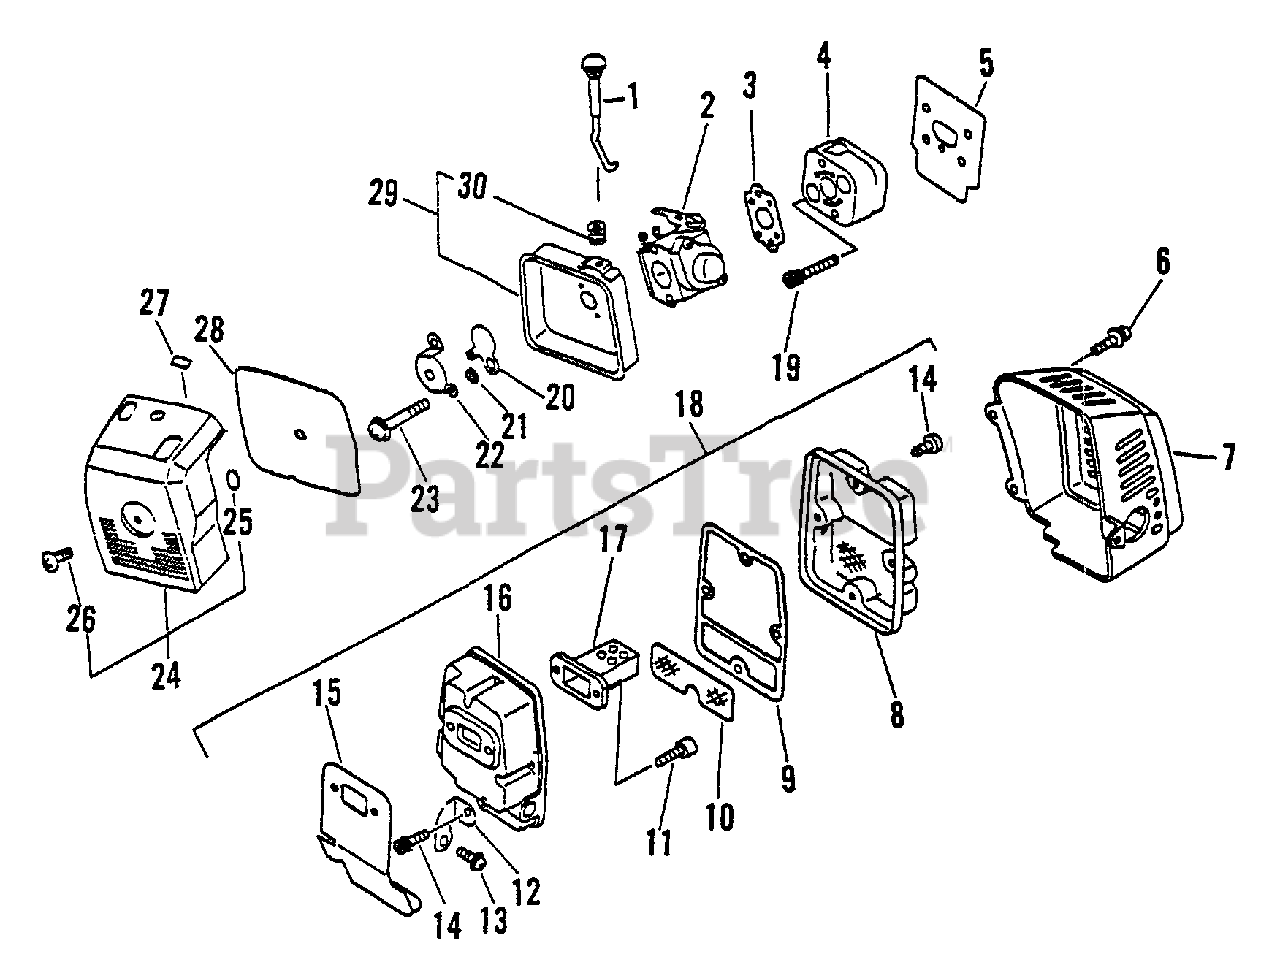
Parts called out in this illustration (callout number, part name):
1	ROD, CHOKE
2	CARBURETOR C1U-K21
3	GASKET, INTAKE
4	INSULATOR
5	GASKET, INTAKE
6	SCREW - 4X8
7	COVER, MUFFLER
8	LID, MUFFLER
9	GASKET, EXHAUST
10	SCREEN, SPARK ARRESTOR
11	SCREW - 5X18
12	BRACKET, MUFFLER
13	SCREW - 5X10
14	SCREW - 5X14
15	GASKET, EXHAUST
16	MUFFLER
17	BAFFLE, MUFFLER
18	MUFFLER ASSY
19	SCREW - 5X25
20	SHUTTER, CHOKE
21	WASHER - 5
22	PLATE, PREVENT
23	SCREW - 5X45
24	AIR FILTER COVER ASSY
25	O-RING - 3
26	THUMBSCREW
27	LABEL - CHOKE
28	FILTER, AIR
28	FILTER, AIR - HEAVY DUTY
29	CASE, AIR FILTER
